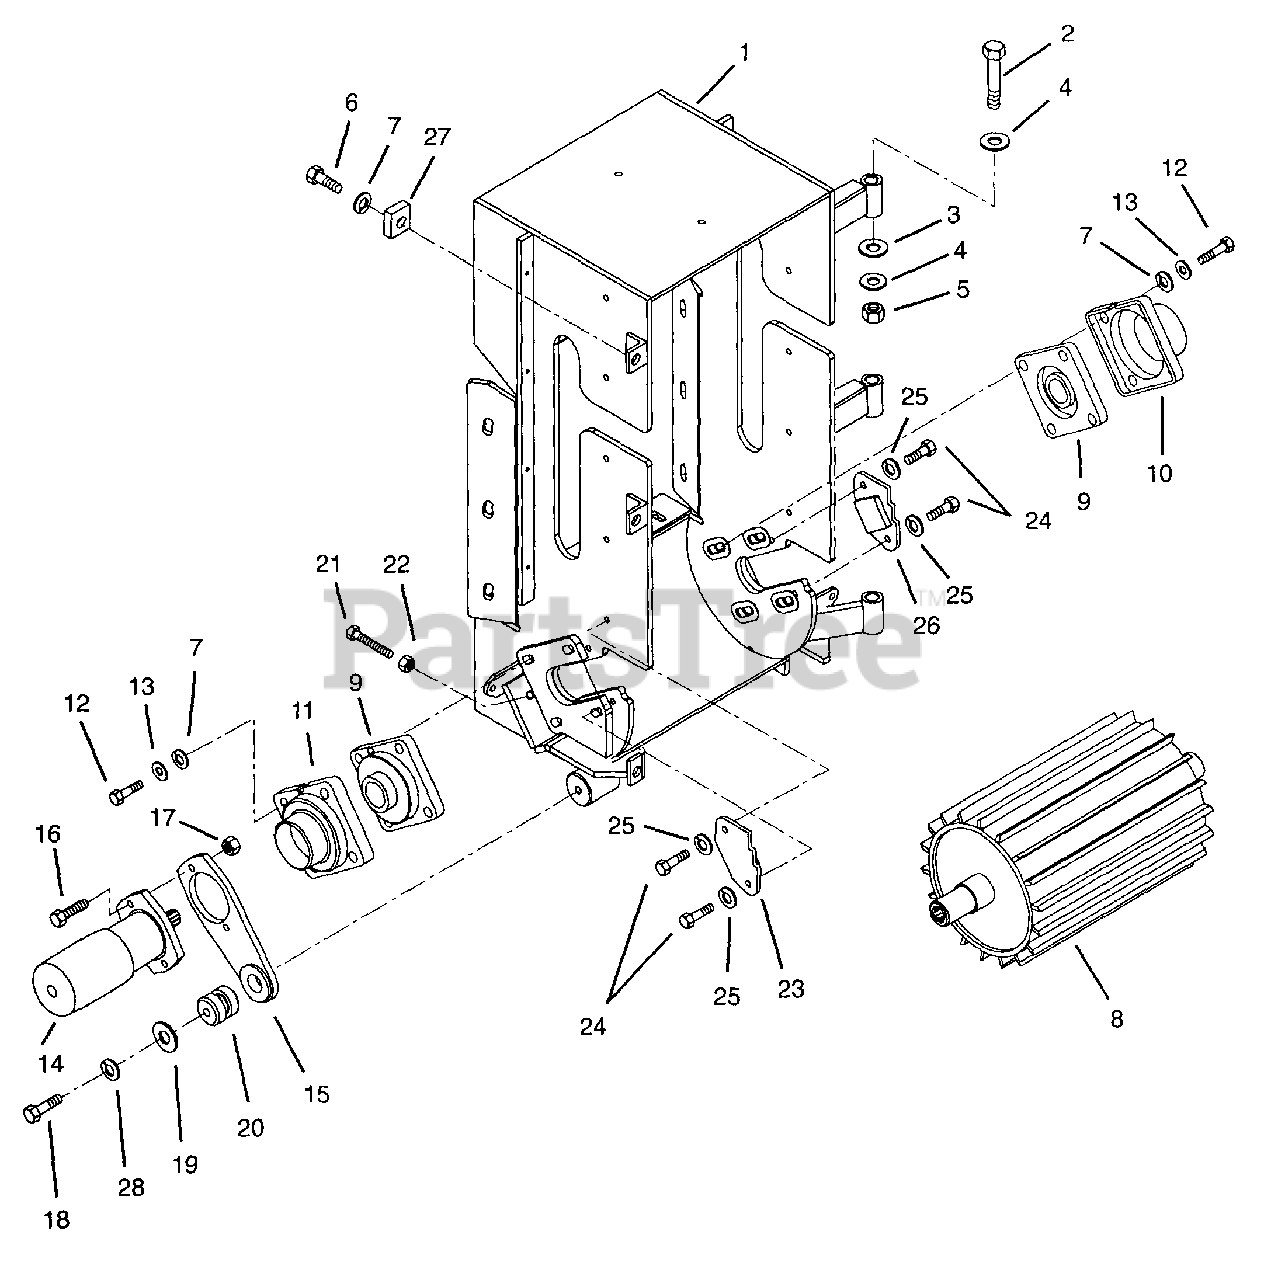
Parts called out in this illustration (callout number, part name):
1	Feed Box Replacement
1	Feed Box Weldment Assembly
2	Bolt-Hex .75-10 x 5.50 Grade 5
3	Washer-Hardened-Thrust .758 x 1.23 x .031
4	Washer-Flat-Steel .812 x 1.50 x .139
5	Nut-Locking-Center .75-10
6	Bolt-Hex .50-13 x 1.75 Grade 5
7	Washer-Lock .50 x .125
8	Roller Weldment-Bottom
9	Bearing-Flange 4-Bolt 1.625
10	Cover Bearing
11	Cover Shaft
12	Bolt-Hex .50-13 x 1.75
13	Washer-Flat-Steel .531 x 1.06 x .095
14	Motor-Hydraulic
15	Torque Arm Weldment
15	Torque Arm Weldment Assembly
16	Bolt-Hex .50-13 x 1.50 Grade 5
17	Nut-Locking-Center .50-13
18	Bolt-Hex .50-13 x 3.00 Grade 5
18	Bolt-Hex .625-11 x 4.00 Grade 8
19	Washer-Flat-Steel .50 x 2.25 x .13
19	Washer-Flat-Steel .656 x 2.25 x .184
20	Rubber Bushing
20	Bushing-Isolation
21	Bolt-Hex .50-13 x 2.25
22	Nut-Hex .50-13
23	Plate-Roller Slot Cover RH Weldment
24	Bolt-Hex .38-16 x .75 Grade 5
25	Washer-Lock .38 x .094
26	Plate-Roller Slot Cover LH Weldment
27	Block-Clamp
28	Washer-Locking .50 x .125
28	Washer-Locking .62 x .156
